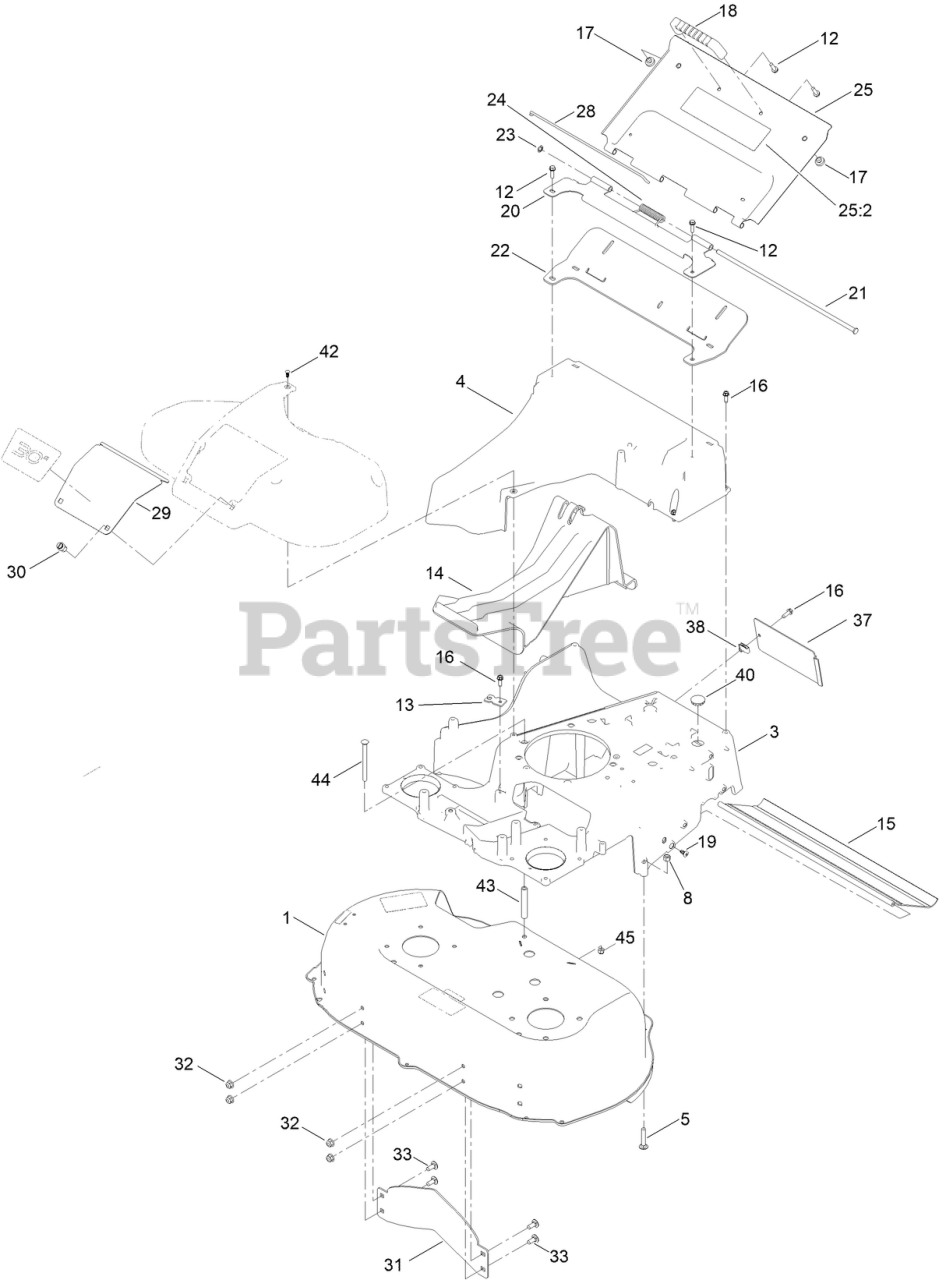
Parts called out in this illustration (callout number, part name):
1	DECK ASM
3	FRAME-30
5	BOLT-CAR
8	NUT-LOCK, NI
12	SCREW-HWH
13	BRACKET-CABLE, TRACTION
14	PLUG-MULCH
15	SHIELD-TRAILING
16	SCREW-HWHTF
17	BUMPER
18	HANDLE-DOOR
19	SCREW-THD
20	BRACKET-HINGE
21	PIN-HINGE
22	SEAL-DOOR
23	RING-RETAINING
24	SPRING-TORSION, COVER
25	REAR DOOR ASM
25:2	DECAL-WARNING
28	CLIP-SEAL
29	DOOR-ACCESS
30	FASTENER
31	BAFFLE-CONTROL
32	NUT-HF, NI
33	SCREW-CARR
37	COVER-FRAME
40	PLUG-BUTTON
42	CLIP-XMAS TREE
43	SPACER
44	BOLT-CARR
45	NUT-HEX
